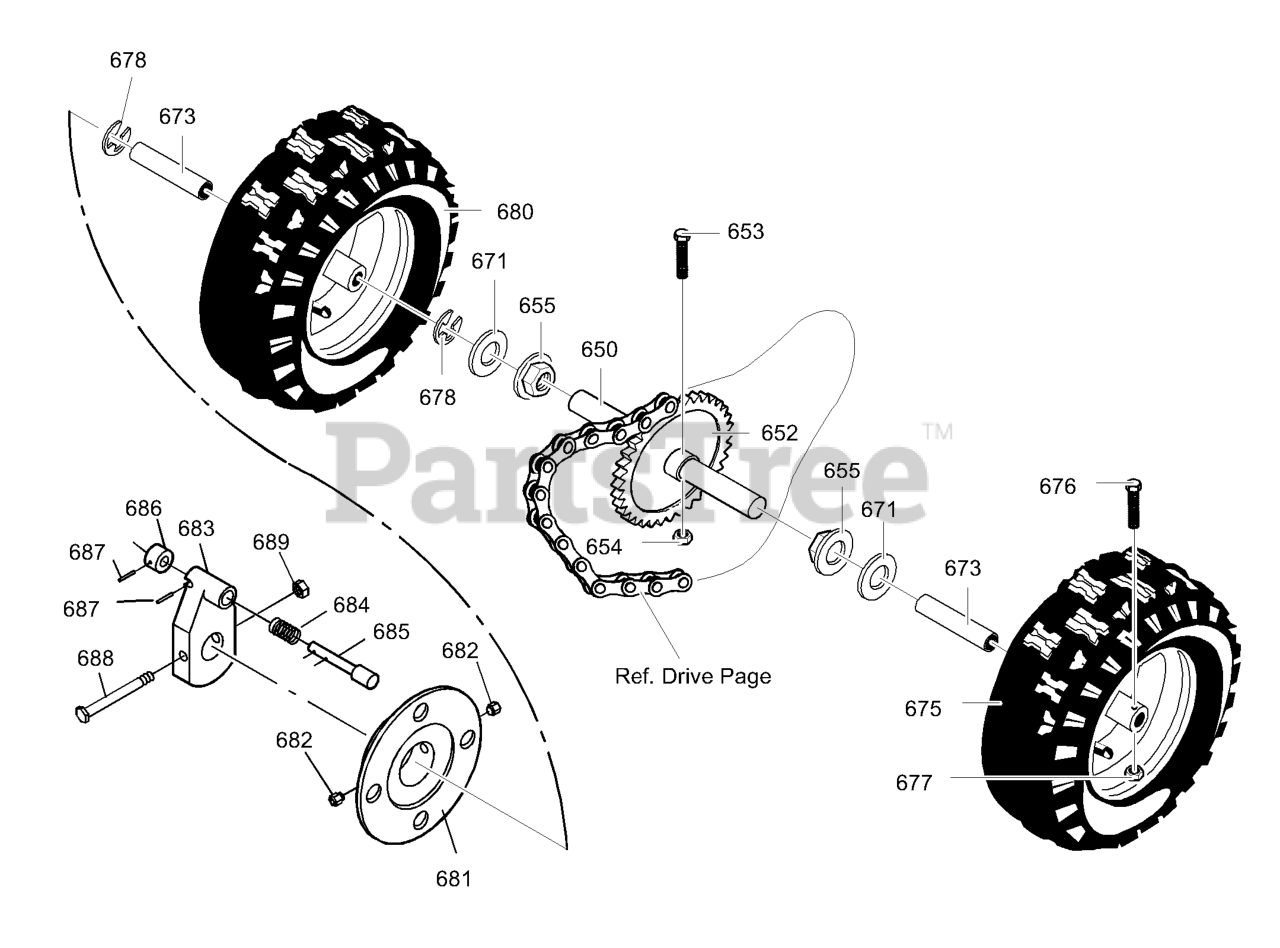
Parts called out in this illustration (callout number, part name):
650	SHAFT, AXLE
652	SPRKT & HUB
653	BOLT, HEX 1/4-20X1.75
654	NUT, 1/4-20 HEX NYLOCK
655	RETAINER, BEARING
671	WASHER, FLAT
673	BUSHING, WHEEL
675	TIRE & RIM -RIGHT
676	SCREW, 1/4-20X1.75 HH
677	NUT, 1/4-20 HEX NYLOCK
678	RING, RET
680	TIRE & RIM -LEFT
681	DISC, WHEEL
683	HUB, WHEEL LOCK
684	SPRING, COMPRESSION
685	PIN, LOCK
689	NUT
